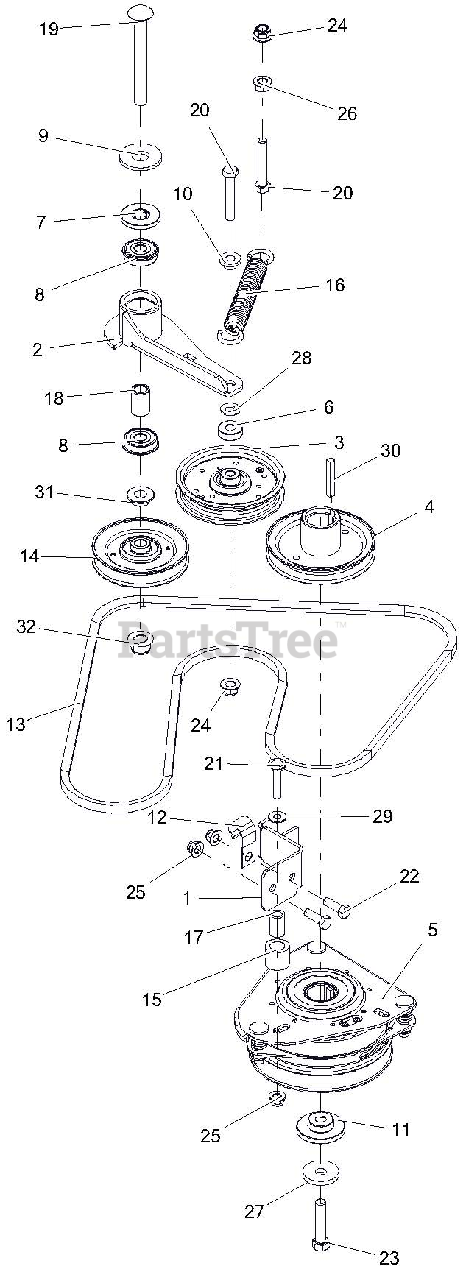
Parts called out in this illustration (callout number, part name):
1	WLDMT, CLUTCH STOP
2	WLDMT, IDLER ARM GROUND DRIVE
3	ASM, IDLER 4"
4	SHEAVE, ENGINE 4.50 X 1.127
5	CLUTCH, ELEC OGURA GT1A-AR03
6	SPCR, .375 X 1.00 X .342
7	SPACER, IDLER ARM
8	BRG, BALL .501 X 1.38 X .438 SEALED
9	WSHR-FL-STL.688X1.75X.134 YWZ
10	BSHG, FLG .385 X .500 X .875 X .406
11	BSHG, -FLG .469 x 1.06 x .574 x 2.0
13	BELT, V- A COGGED
14	SHEAVE, IDLER -V .50 X 4.000
15	BUMPER, RUBBER .62 X 1.0 X .88 LG
16	SPRG, EXTENSION
17	BUSH.,S.391X.622X.95 ST REV A
18	SPACER, .510 X .750 X 1.148
19	BLT-RDHDSQNK .50-13X4.50 G5 YWZC
20	BLT-HEX .38-16X2.25 GR5 YWZC
21	BLT-HEX .31-18X1.50 GR5 YWZC
22	BLT-HEX .31-18X1.00 GR5 YWZC
23	BLT-HEX .44-20X2.00 GR8 YWZC NYTORQ
24	NUT-LK-NYL-FLG .38-16 YWZC
25	NUT-LK-NYL-FLG .31-18 YWZC
26	@NUT-SPNLK-FLG .375-16 YWZC
27	WSHR, 7/16" SPRING DISC
28	WSHR-FL-STL.406X.812X.065 YWZ
29	WSHR-FL-STL.312X.734X.065 YWZ
30	KEY-STR .25X1.75X.25
31	BSHG, FLANGE .515X.750X.420X1.12
32	NUT-LK-NYL-FLG .50-13 YWZC
